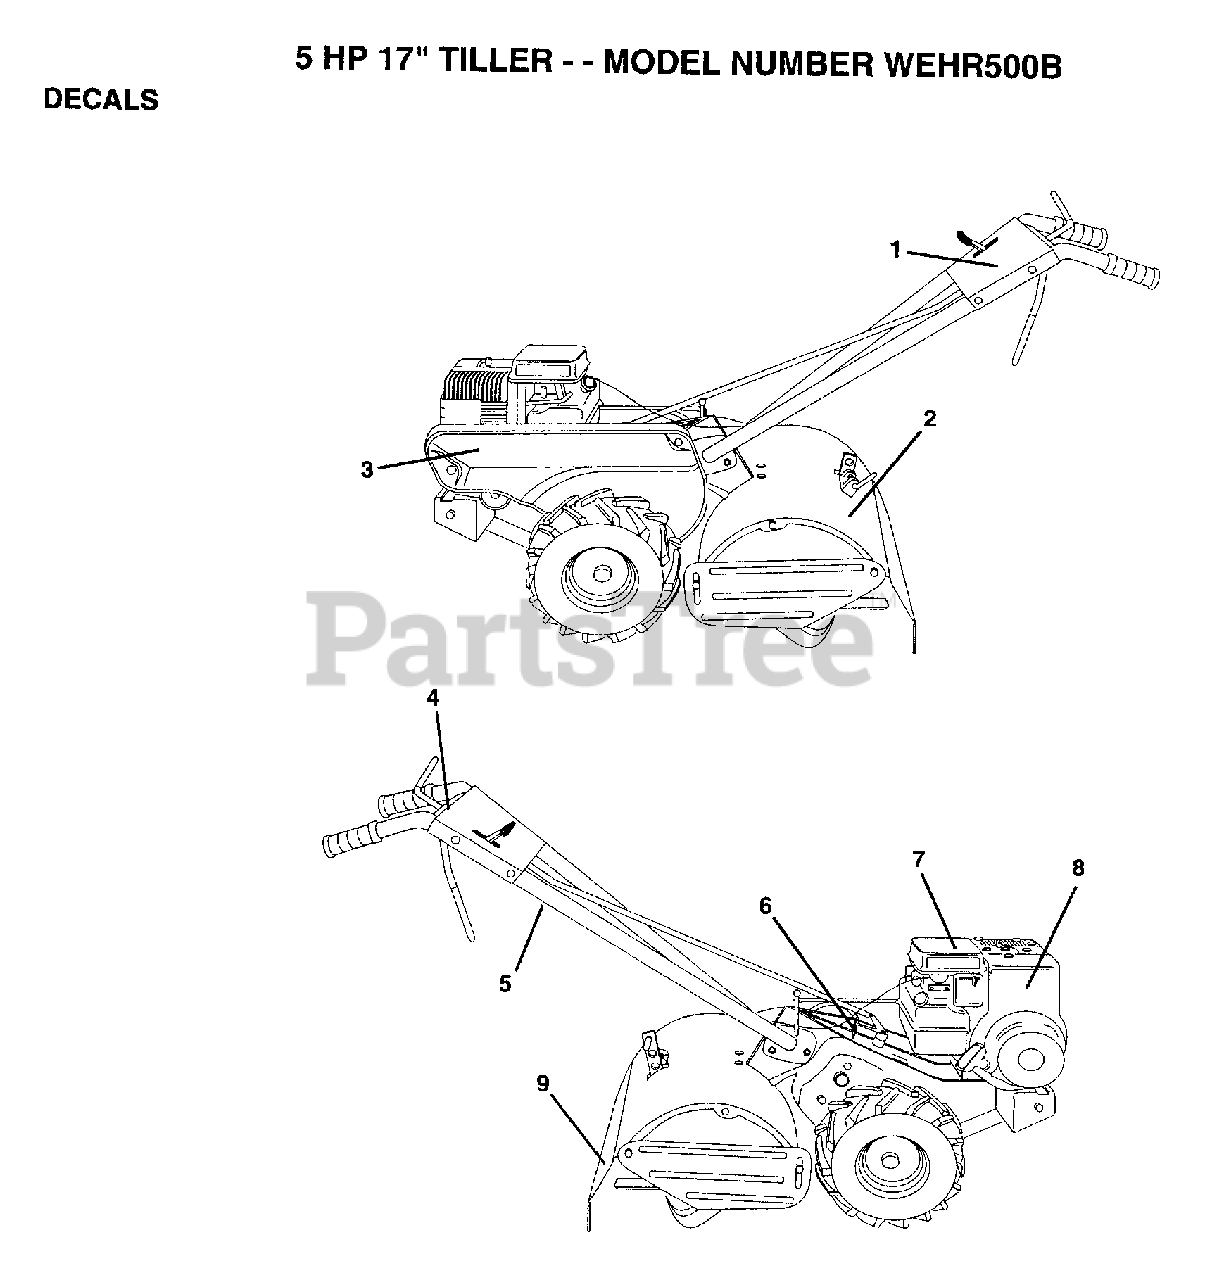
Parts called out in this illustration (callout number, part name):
1	DECAL LOGO 17 5HP
2	DECAL SHIELD TINE
3	DECAL BELT GUARD
4	DECAL.CONTROL
5	DECAL.HAND.PLACE
6	DECAL CRT
7	DECAL.CAUTION.E/S
9	DECAL.WARN.ROT.TI
